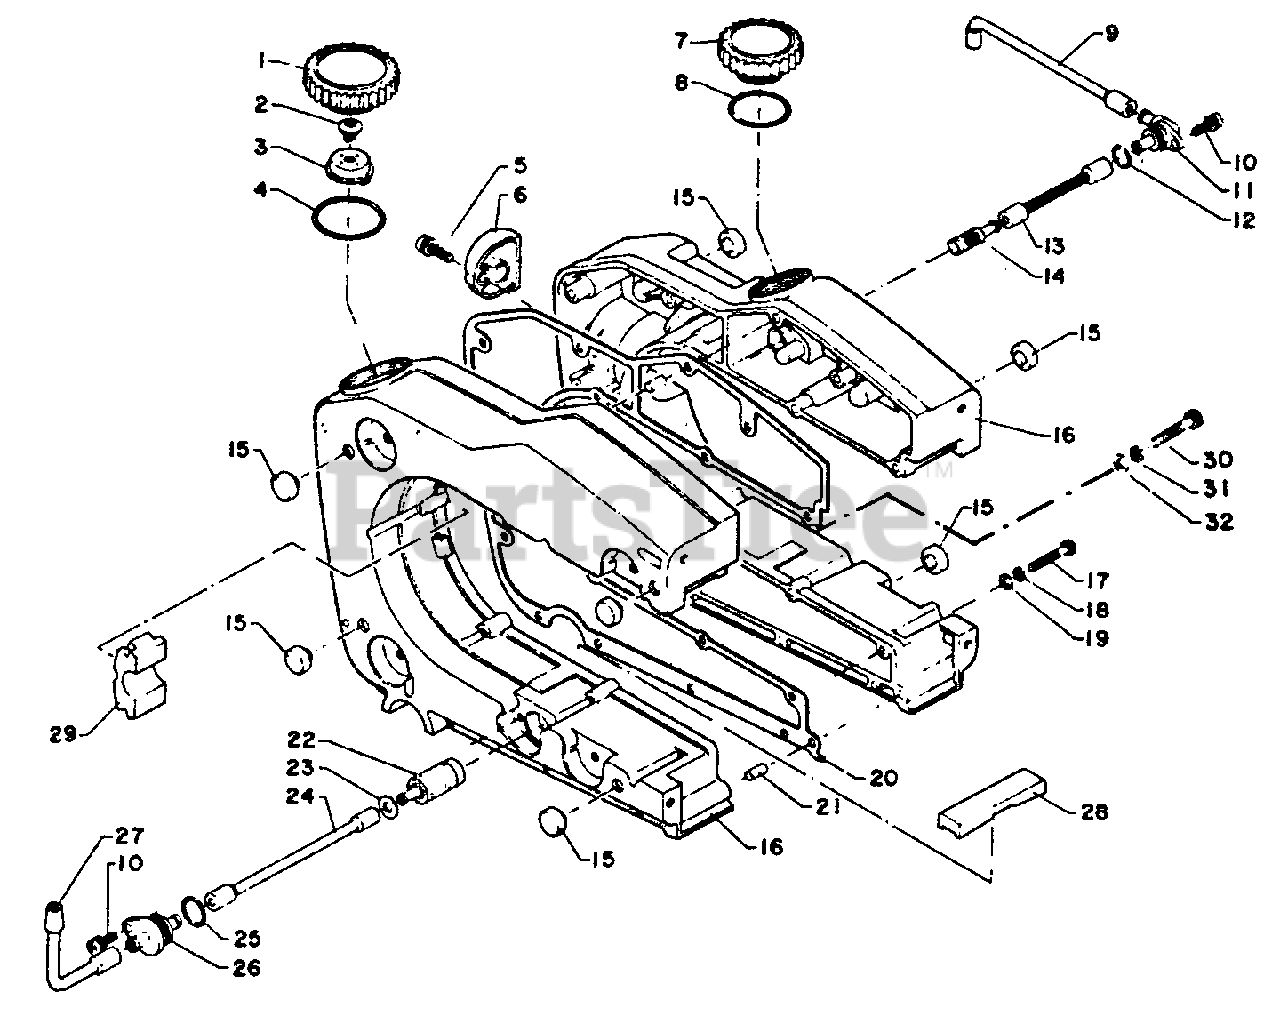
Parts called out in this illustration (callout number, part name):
1	CAP ASSY
3	HOLDER, VENT
4	O-RING - 29
5	SCREW - 5X15
6	COVER, OIL PUMP
7	CAP, OIL TANK
8	O-RING - 25
9	PIPE, OIL - OUTER
10	SCREW - 4X12
11	CONNECTOR, PIPE
12	O-RING - 9
13	PIPE - INNER
14	FILTER, OIL
15	CUSHION
16	TANK, FUEL
17	SCREW - 4X25
18	LOCKWASHER - 4
19	WASHER - 4
20	GASKET, FUEL TANK
21	PIN - LOCATING
22	FILTER, FUEL
23	WASHER - 6
24	PIPE - INNER
25	O-RING - 12
26	CONNECTOR, PIPE
27	PIPE - FUEL
28	CUSHION
29	STOPPER
30	SCREW - 5X25
31	LOCKWASHER - 5
32	WASHER - 5
